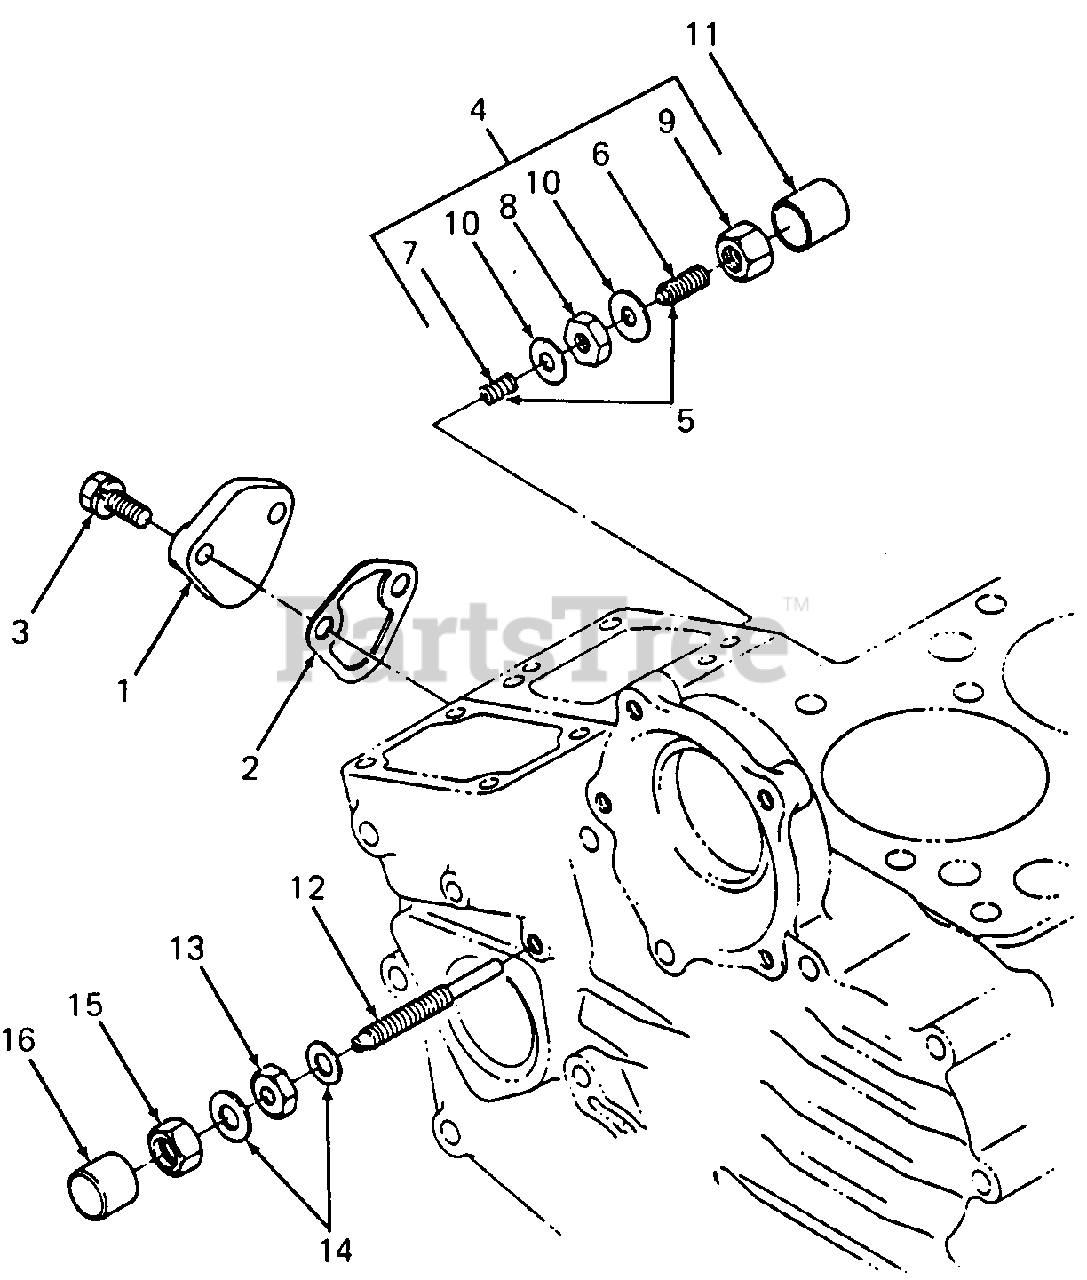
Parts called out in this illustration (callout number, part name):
3	Screw, Hex Cap w/Washer
4	Bolt Assy, Idling
5	Bolt Assy, Adjusting
12	Bolt, Adjusting
